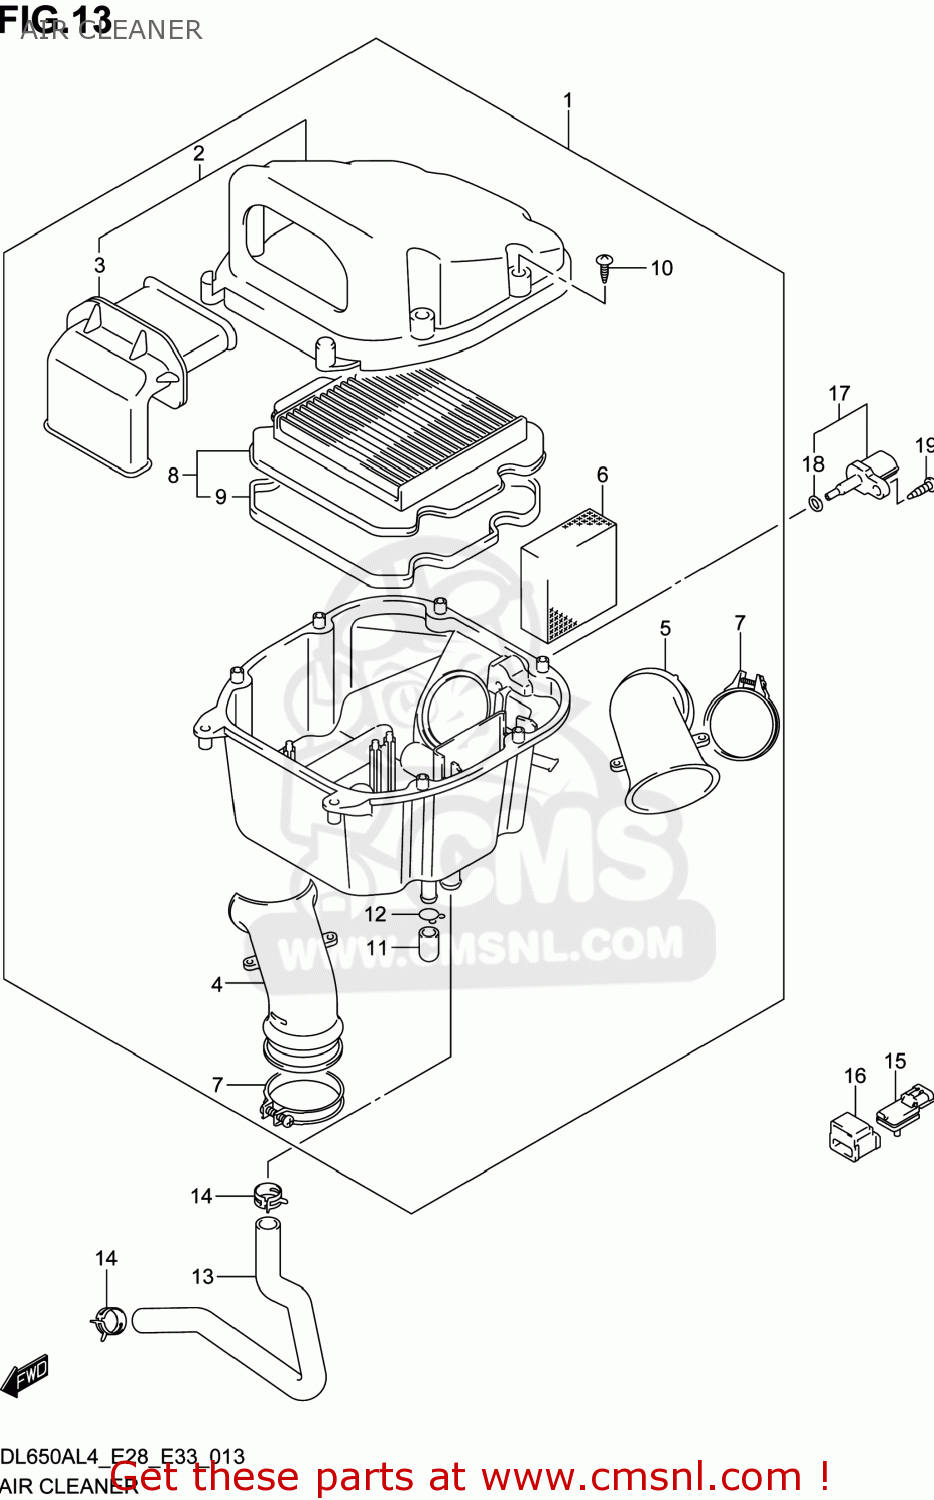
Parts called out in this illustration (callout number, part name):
1	CLEANER ASSY,AIR
2	CAP,AIR CLEANER
3	TUBE,INLET
4	TUBE,OUTLET
5	TUBE,OUTLET
6	FILTER,BREATHER
7	CLAMP,OUTLET TUBE
8	FILTER ASSY
9	GASKET,AIR CLEANER (NAS)
10	SCREW
11	PLUG
12	CLIP
13	TUBE,BREATHER
14	CLIP
15	SENSOR,PRESSURE
16	HOLDER,SENSOR
17	SENSOR,AIR TEMP
18	O RING
19	SCREW
